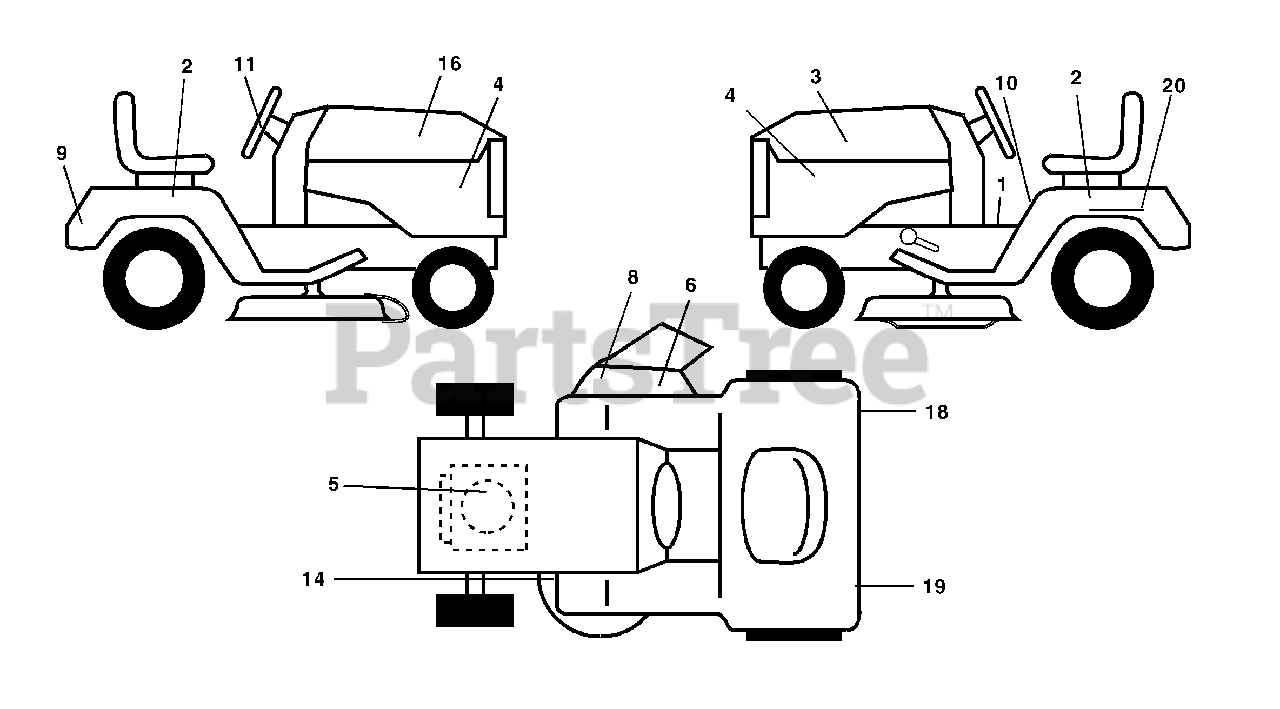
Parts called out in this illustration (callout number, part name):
2	Decal Fender Side
3	Decal Hood LH
4	Decal Side Panel Logo
5	Decal HP Engine
6	Decal Deck "B" 42"
8	Decal Warning Mult-Language
9	Decal Fender Logo
10	Decal Fender Danger E/F
11	Decal Ins Strg Whl
14	Decal V-Belt Schematic
16	Decal Hood Rh
18	Decal Fender Reflector RH
19	Decal Fender Reflector LH
20	Decal Bat Dan/Psn
